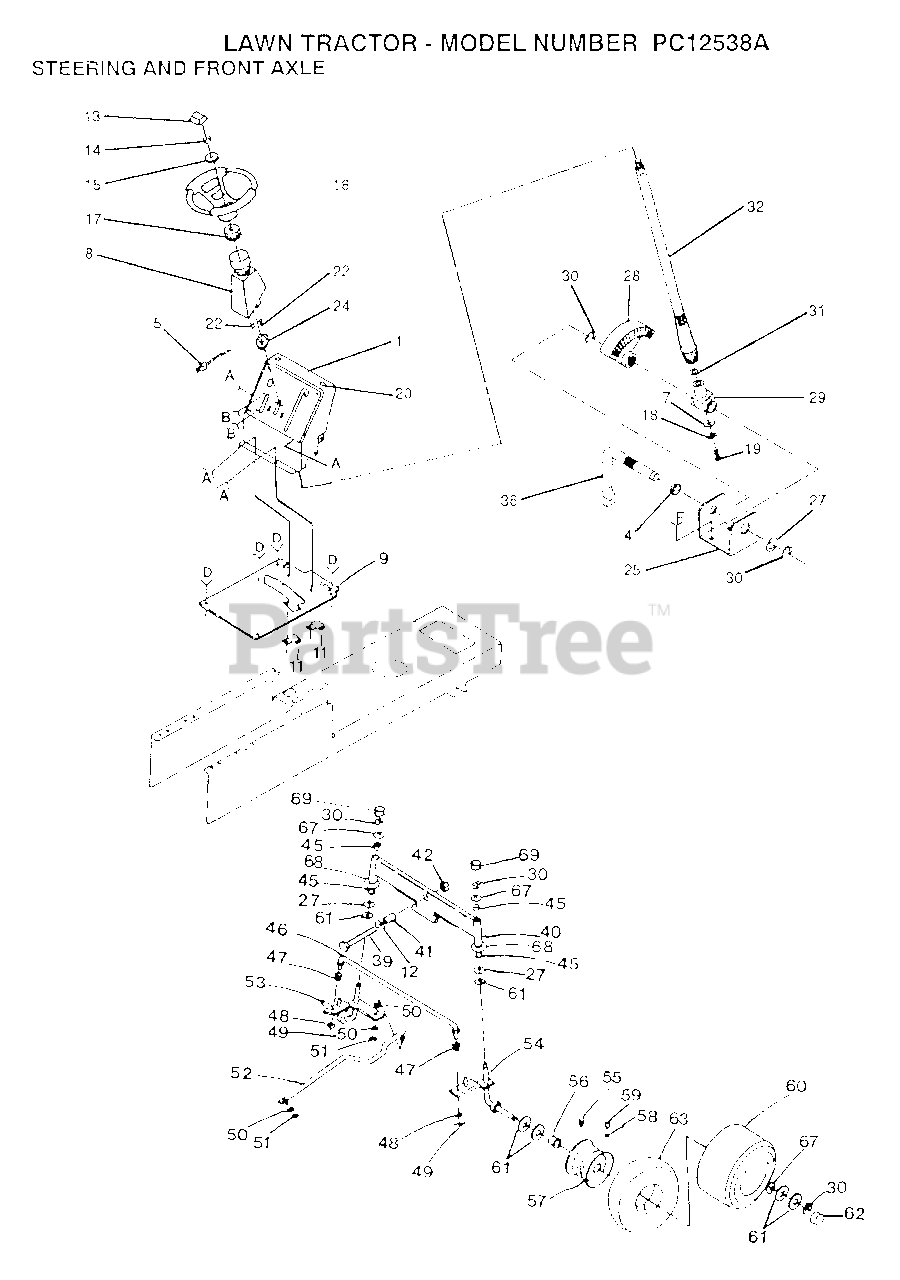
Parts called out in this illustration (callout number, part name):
2	SCREW
4	NYLINER T
6	SCREW LT
8	"TUBE, STR SHAFT"
10	SCREW LT
11	CLIP T
13	INSERT-WHEEL LT
15	WASHER
17	ADAPTER LT
18	LOCKWASHER
19	"SCREW,SPECIAL"
24	"BUSHING,STEERING"
25	"BRKT,STEERING"
26	SCREW
27	WASHER .T
29	SUPPORT.SHAFT
30	RING
31	THRUST WASHER
32	SHAFT WELD STR T
39	BOLT LT
41	BEARING
45	COL. SRTG. BEAR.
46	ROD TIE
47	WASHER M
48	LOCKWASHER
49	NUT.LOCK.5/16-24
50	LOCKWASHER
53	SPINDLE-LH LT
55	FITTING LT
56	"FLANGE, BEARING"
58	VALVE CAP
59	VALVE STEM LT
61	WASHER
62	HUB CAP
63	TUBE.5.3/4.5/6
67	WASHER
68	WASHER
69	CAP
